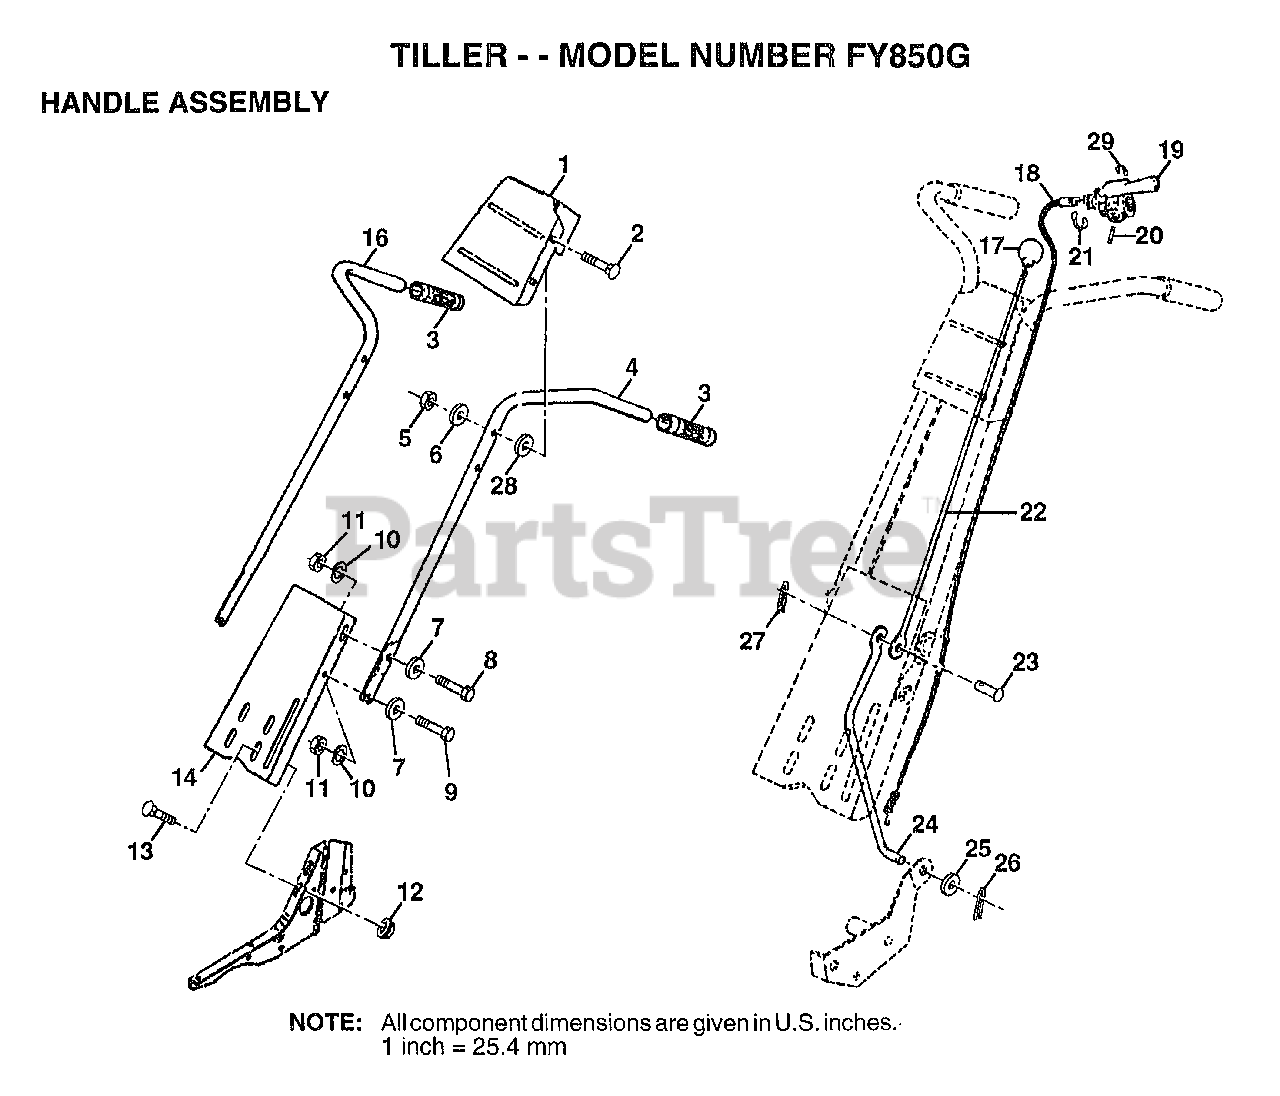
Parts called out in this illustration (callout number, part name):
2	BOLT
4	HANDLE.LH TILLER
6	WASHER
7	WASHER
9	BOLT
10	LOCKWASHER
11	NUT.HEX.5/16-18
12	NUT
13	BOLT
16	"HANDLE-RH,TILLER"
17	KNOB T(3/8 HOLE)
18	CABLE CLUTCH T
19	LEVER CONTRL TINE
20	"PIN PIVOT,GROOVED"
21	E-RING
22	ROD REVERSE TI
23	RIVET.RD.HD.DRILL
24	REVERSE ROD TI
25	WASHER
26	COTTER PIN
28	WASHER
29	RETAINER RING
